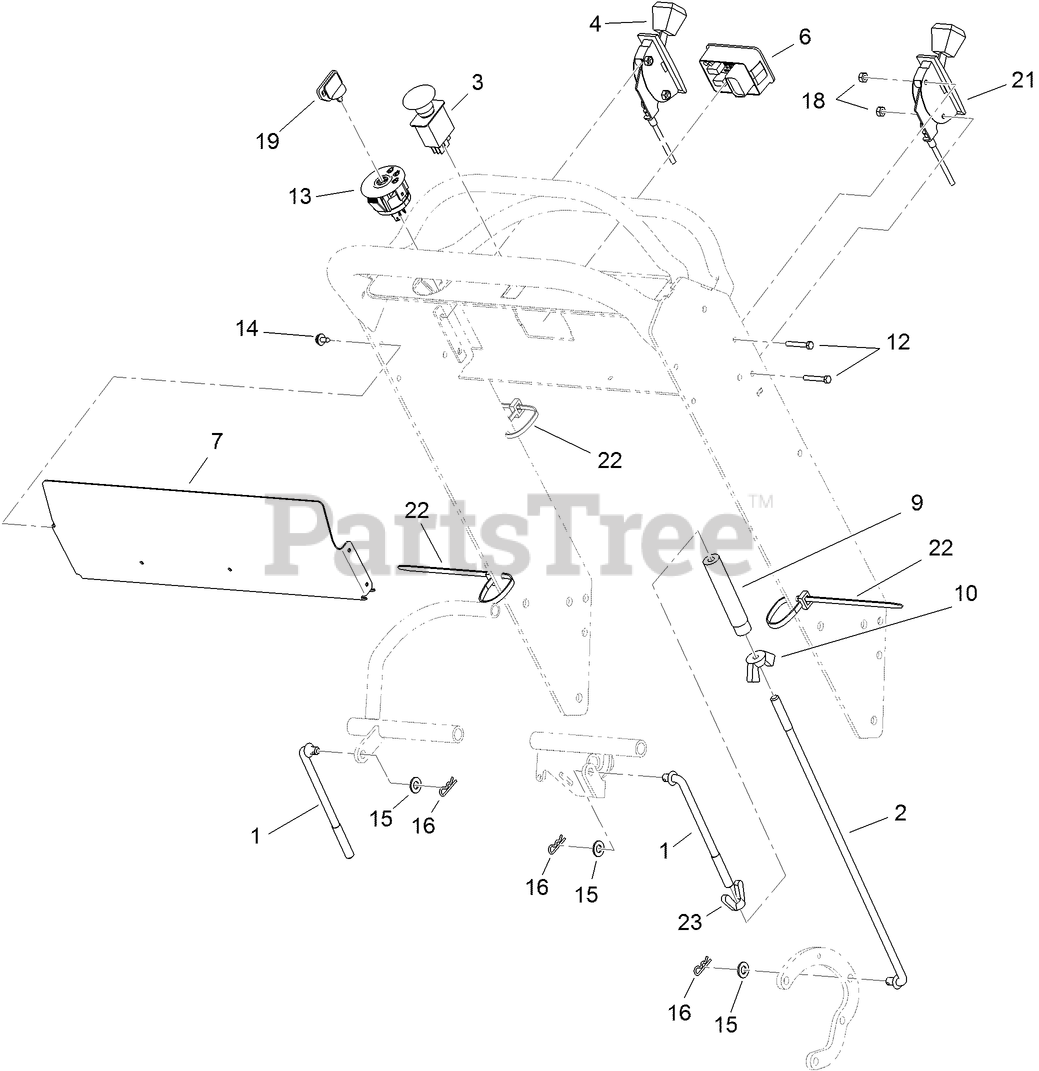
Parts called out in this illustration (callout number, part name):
1	ROD-CONTROL, UPPER
2	ROD-CONTROL, LOWER
3	SWITCH-PTO, ON-ON-(ON)
4	CABLE-THROTTLE
6	MODULE-HOUR METER
7	COVER-PANEL, CONTROL
9	TURNBUCKLE
10	NUT-WING
12	SCREW-HH
13	SWITCH-IGNITION
14	SCREW-HWHTF
15	WASHER-PLAIN
16	PIN-COTTER
18	NUT-LOCK, NI
19	KEY-IGNITION
21	CABLE-CHOKE
22	TIE-CABLE
23	NUT-WING, LH
